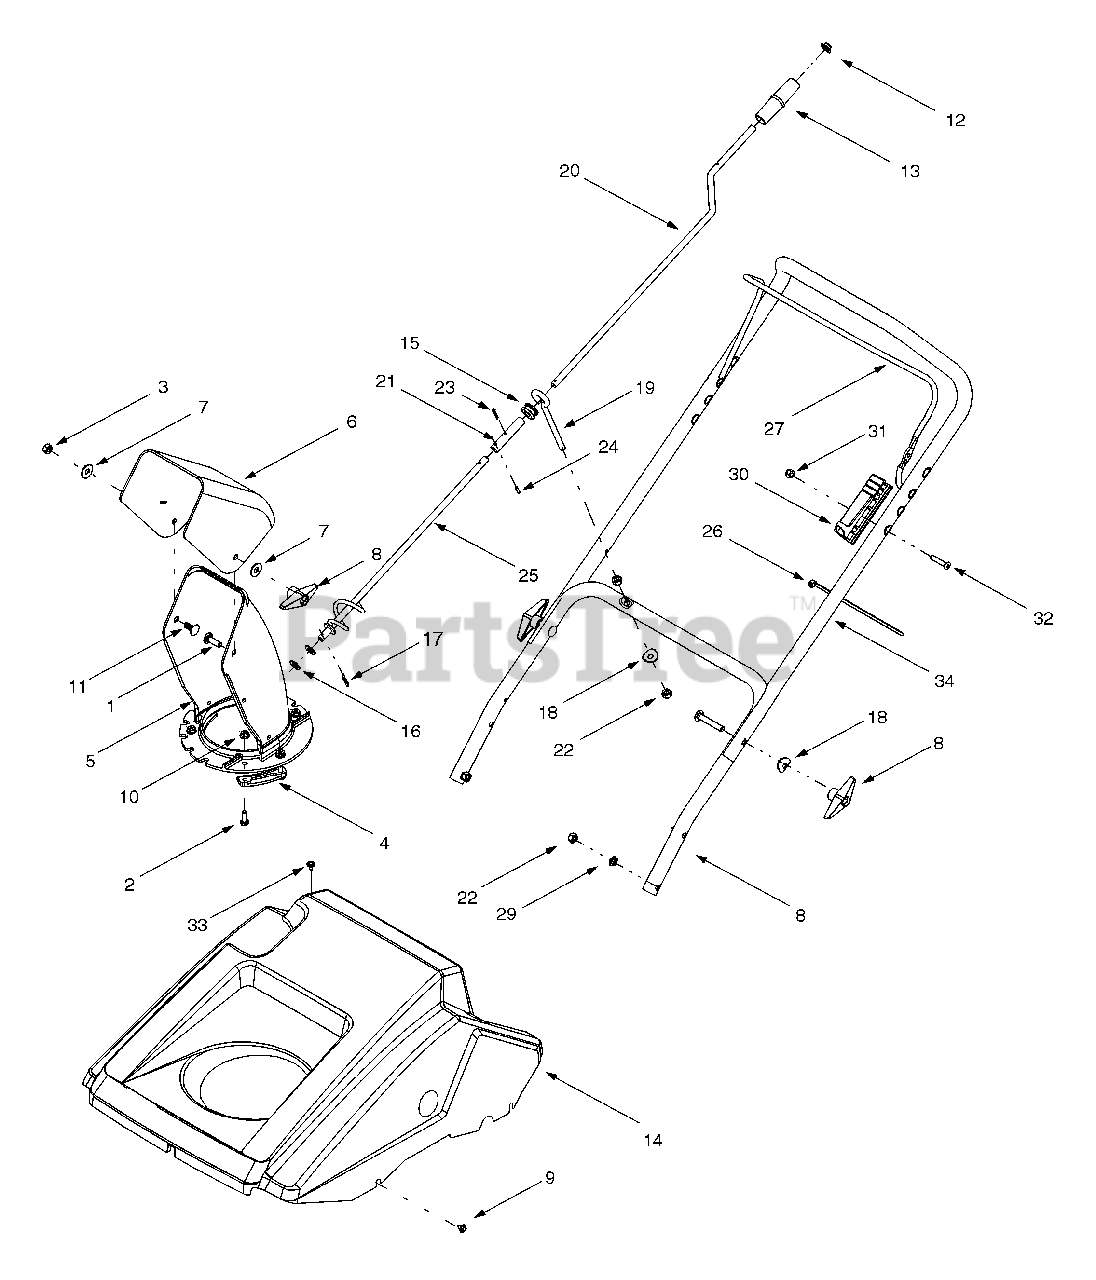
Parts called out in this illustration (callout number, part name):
1	Splined Carriage Screw, 5/16-18 x 1.0
2	Hex Cap Screw, 1/4-20 x.75
3	Hex Lock Nut, 5/16-18
4	Chute Flange Keeper
5	Lower Chute, 5.0
6	Upper Chute, 5.0
7	Washer, .349 x .879 x .063
8	Wingnut Knob, 5/16-18
9	Screw, #10-16 x .375
10	Hex Flange Lock Nut, 1/4-20
11	Carriage Bolt, 5/16-18 x .75
12	Push Cap, 3/8
13	Knob, 1.0 x 3.2
14	Shroud, Beige
15	Rubber Grommet, .44 x .94 x .50
16	Flat Washer, .375 x .738 x .063
17	Internal Cotter Pin, .072 x 1.12
18	Saddle Washer, .320 x .93
19	Eyebolt, .70
21	Spacer, .382 x .50 x 1.12
22	Hex Nut, 5/16-18
23	Cotter Pin, 3/32 x .75
24	Rolled Pin, 1/8 x .63
30	Control (Cable) Housing
31	Nylon Hex Lock Nut, 1/4-20
32	Machine Screw, 1/4-20 x 1.31
33	Screw, #10-16 x .625
